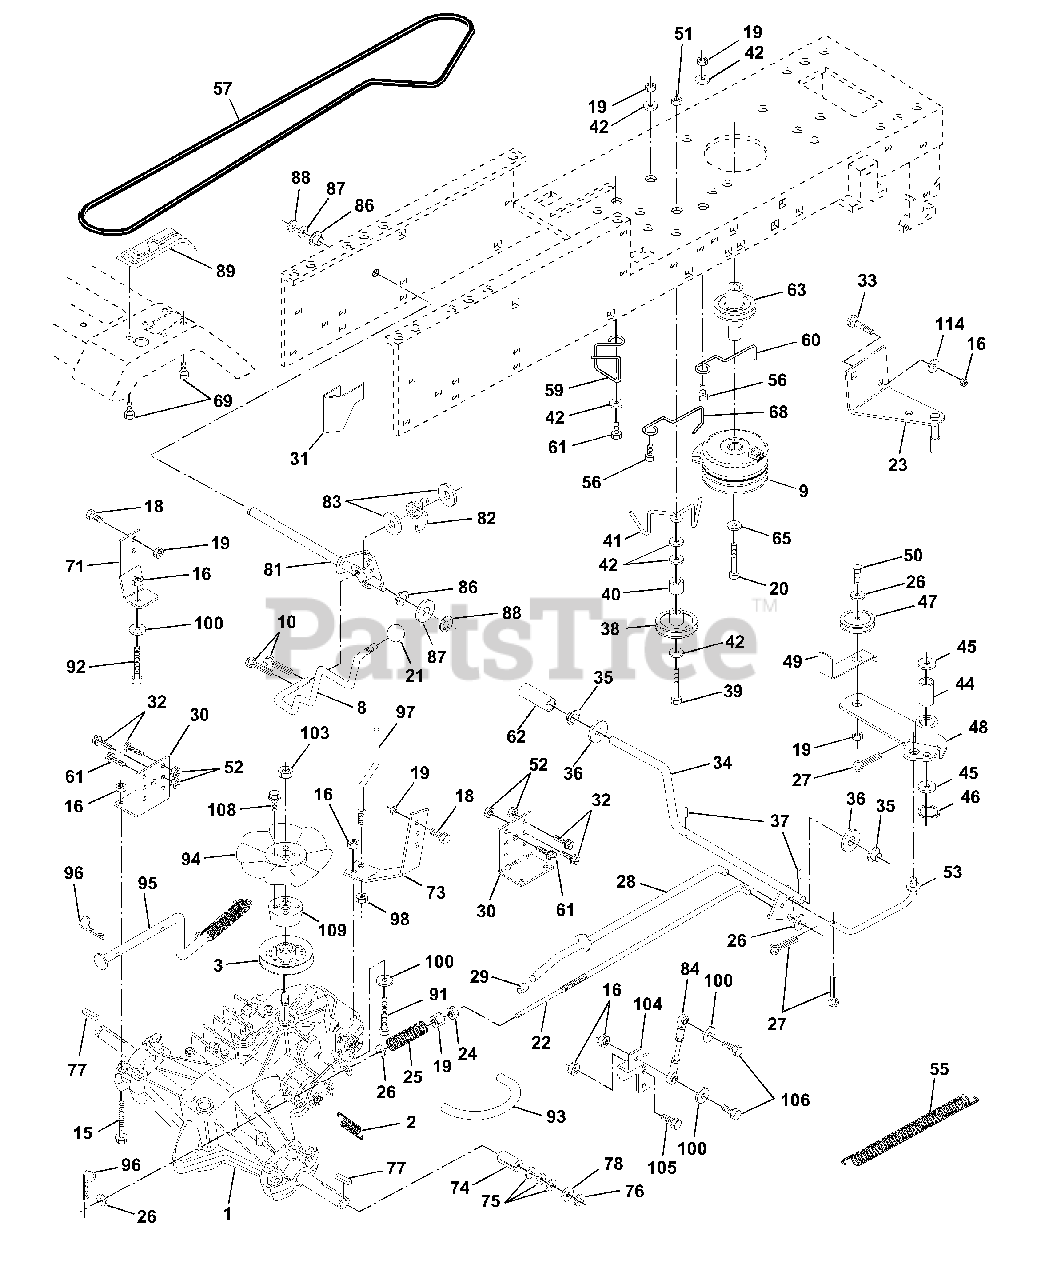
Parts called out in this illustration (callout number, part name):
1	Transaxle Assembly
2	Spring, Return, Brake
3	Pulley, Transaxle
8	Rod Shift Fender LT
9	Clutch, Elect. EVX LT Mag 5217-2
10	Pin Cotter 1/8 x 1 CAD
15	Bolt Hex Flghd 5/16-18 Gr. 5
16	Nut Lock Hex W/Ins. 5/16-18 Unc P
18	Bolt Fin Hex 3/8-16 Unc x 1 Gr. 5
19	Nut Lock Hex W/Wsh 3/8-16 Unc
20	Bolt Hex 7/16-20 x 4-1/4 Ga. 5
21	Knob, Duckhead 1/2-13
22	Rod, Brake Hydro
23	Bracket, Asm Clutch Mtg EVX
24	Nut
25	Spring, Brake Rod
26	Washer
27	Pin Cotter 1/8 x 3/4 CAD.
28	Rod, Parking Brake
29	Cap, Parking Brake
30	Bracket, Transaxle
31	Keeper Belt Lh
32	Bolt Hex Hd 5/16-18 Unc x 3/4
33	Bolt Rdhd Sqnk 5/16-18 UNC x 3/4
34	Shaft, Foot Pedal
35	Bearing, Nylon
37	Pin, Roll
38	Pulley, Idler, Flat
40	Spacer, Split
41	Keeper, Belt Retainer
42	Washer 13/32 x 13/16 x 12 Gauge
44	Bearing, Nylon
45	Washer, Hardened
46	Ring, Klip
47	Pulley, Idler, V-Groove
48	Bellcrank Assembly
49	Retainer, Belt
50	Bolt
52	Nut Crownlock 5/16-18
53	Link, Clutch
55	Spring, Return, Clutch
56	Bolt Fin Hex 3/8-16 UNC x 1-1/4
57	V-Belt, Ground Drive
59	Keeper, Center Span
60	Keeper Belt Engine
61	Screw Thdrol. 3/8-16 x 3/4 Ty. TT
62	Cover, Pedal
63	Pulley, Clutch Electric EVX
65	Washer
68	Keeper Belt Engine
71	Strap Torque Lh Hydro
73	Strap Torque Rh Hydro
74	Spacer, Split
75	Washer 25/32 x 1-1/4 x 16 Gauge
77	Key, Square
78	Washer 25/32 x 1-5/8 x 16 Gauge
81	Shaft Asm. Cross Hydro
82	Spring Torsion T/A
83	Washer 17/32 x 3/4 x 16 Ga.
84	Rod, Tie Hydro
86	Bushing Rod Steering 629/632 ID
87	Washer 21/32 x 1-1/4 x 16 Ga.
88	Ring Klip #5304-62
89	Console, Shift
91	Bolt Fin Hex 5/16-18 x 2-1/4
92	Bolt Fin Hex 5/6-18 Unc x 1-1/2
93	Line Fuel Hydro 4"
94	Fan, Hydro 7"
95	Control Asm Bypass Hydro
96	Retainer Spring 1" Zinc/Cad
97	Keeper Belt Rh Hydro
98	Nut Keps Hex 3/8-16 Unc
100	Washer 11/32 x 3/4 x 16 Ga.
103	Nut Nylon Insert 1/2-20 Unf.
104	Arm, Control Hydro
105	Screw Cap Hex 5/16 x 18 x 1
106	Bolt Fin Hex 5/16-18 Unc x 1-1/4
108	Screw Hex Wh Hd #10-24 x
109	Adaptor Fan Hydro LT Hyd Alum
114	Washer 11/32 x 3/4 x 14 Ga.
